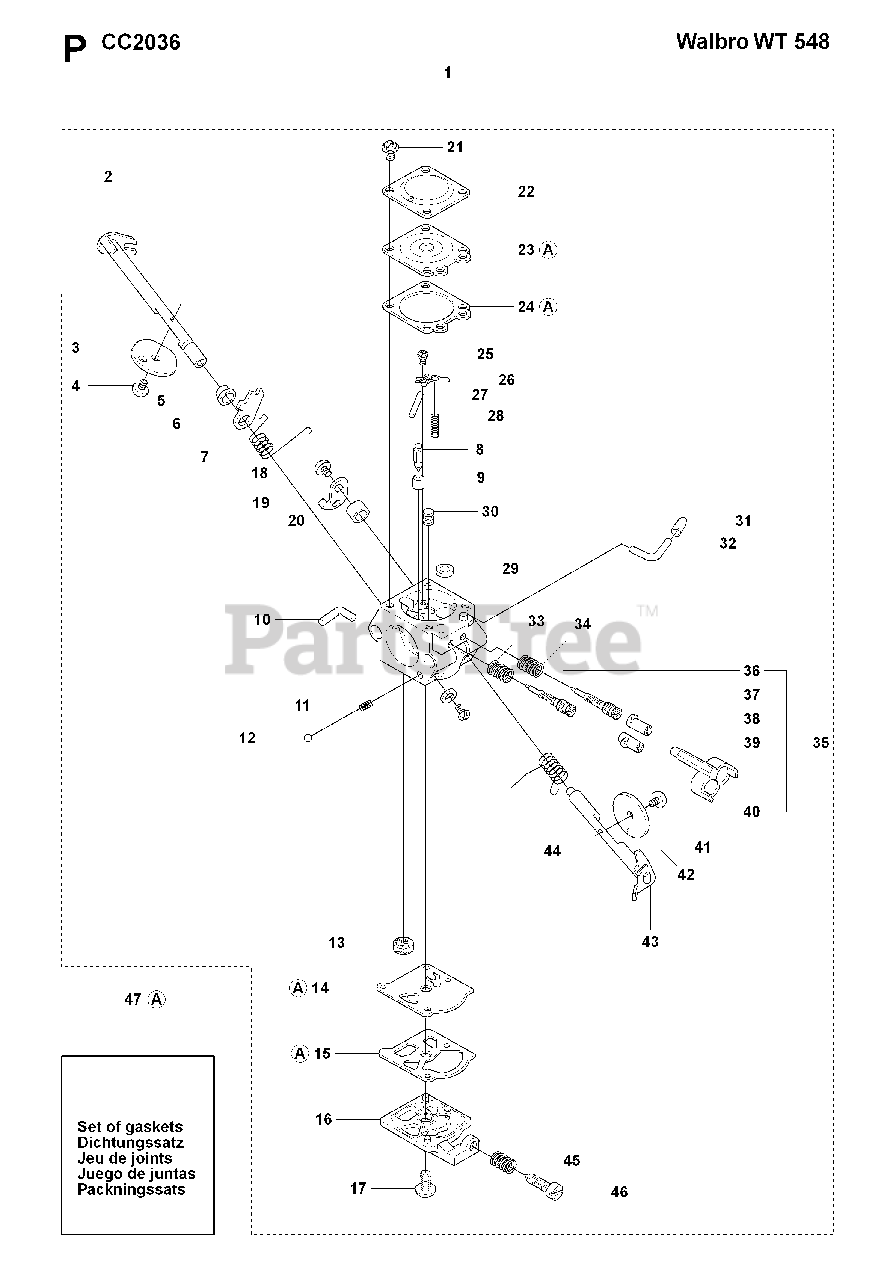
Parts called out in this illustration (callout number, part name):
1	%CARBURETOR WT548 WALBRO
2	CHOKE SHAFT
6	STARTER LEVER
8	VALVE/INLET.
13	FUEL INLET SCREEN
14	PUMP DIAPHRAGM
19	LEVER, THROTTLE
21	SCREW W/ WASHER
22	DIAPHRAGM COVER
23	DIAPHRAGM
24	GASKET, METERING SIDE
27	FULCRUM PIN
29	WELCH PLUG
33	SPRING, H-NEEDLE
34	SPRING/COMPRESSION
35	LIMITER CAP & SCREW SET
37	ADJUSTING SCREW
38	LIMITER CAP
39	LIMITER CAP
42	THROTTLE FLAP
47	GASKET SET (WT202)
